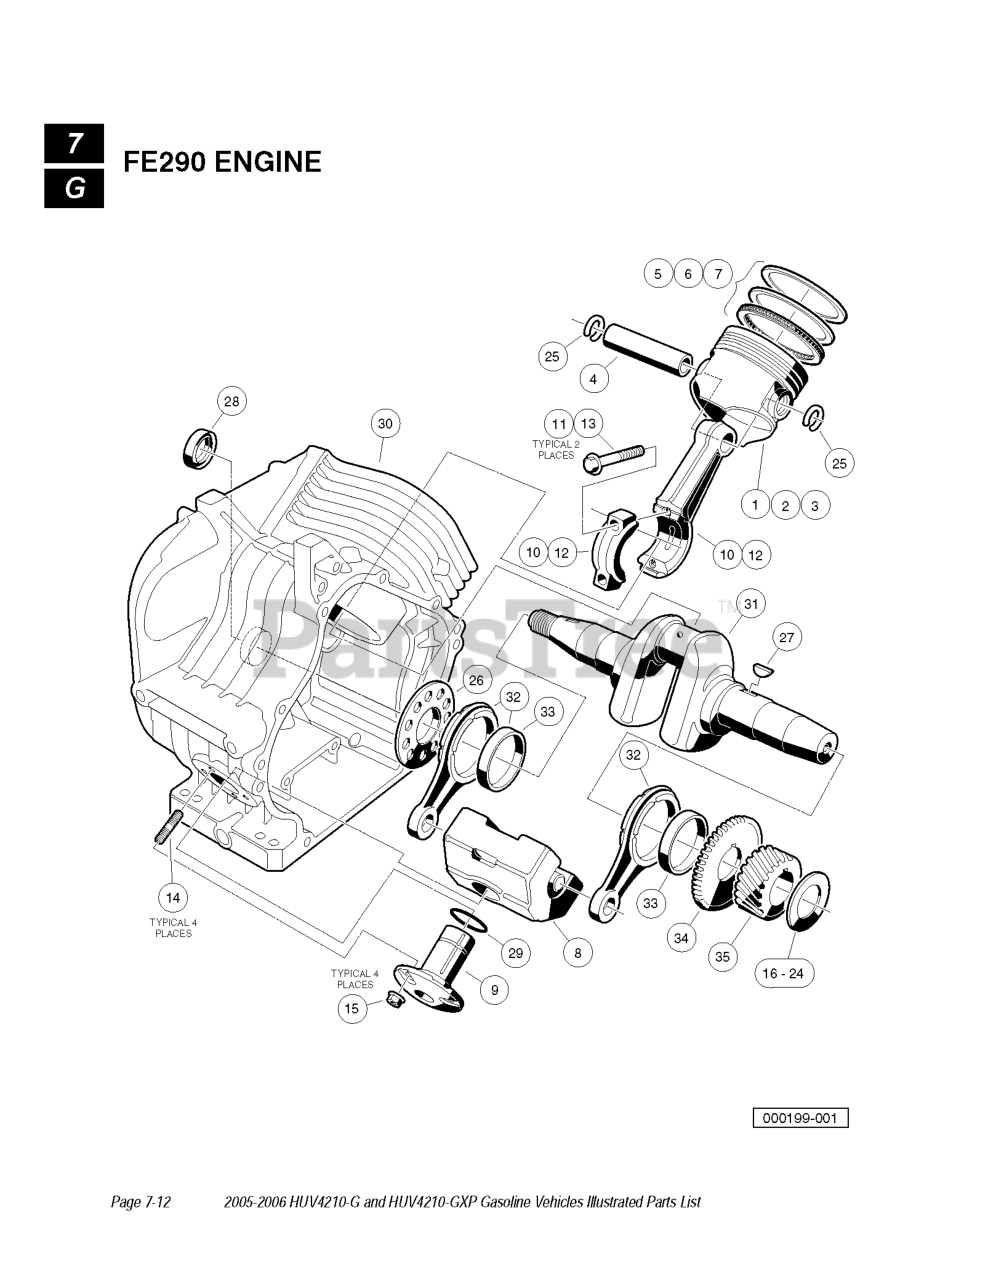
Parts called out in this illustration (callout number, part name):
1	PISTON, ENGINE STD OHV
2	PISTON, ENGINE .25MM OVER
3	PISTON, ENGINE .50MM OVER
4	PIN - PISTON
5	RING-SET-PISTON STD
6	RING-SET-PISTON .25MM OVER
7	RING-SET-PISTON .50MM OVER
8	WEIGHT, COUNTER - BALANCE
9	SHAFT, GUIDE, COUNTER-BALANCE
10	ASM, CONNECTING ROD STD
12	ASM, CONNECTING ROD 0.5MM U/S
14	STUD, 6X14
16	SHIM, CRANKSHAFT T=1.13
17	SHIM, CRANKSHAFT T=1.18
18	SHIM, CRANKSHAFT T=1.23
19	SHIM, CRANKSHAFT T=1.28
20	SHIM, CRANKSHAFT T=1.33
21	SHIM, CRANKSHAFT T=1.38
22	SHIM, CRANKSHAFT T=1.43
23	SHIM, CRANKSHAFT T=1.48
24	SHIM, CRANKSHAFT T=1.53 OHV
25	RING, SNAP
30	CRANKCASE COMPLETE, FE290 CW
31	CRANKSHAFT, FE290 LH THREAD
33	BEARING , PLANE OHV
34	GEAR, SPUR
35	GEAR, HELICAL
